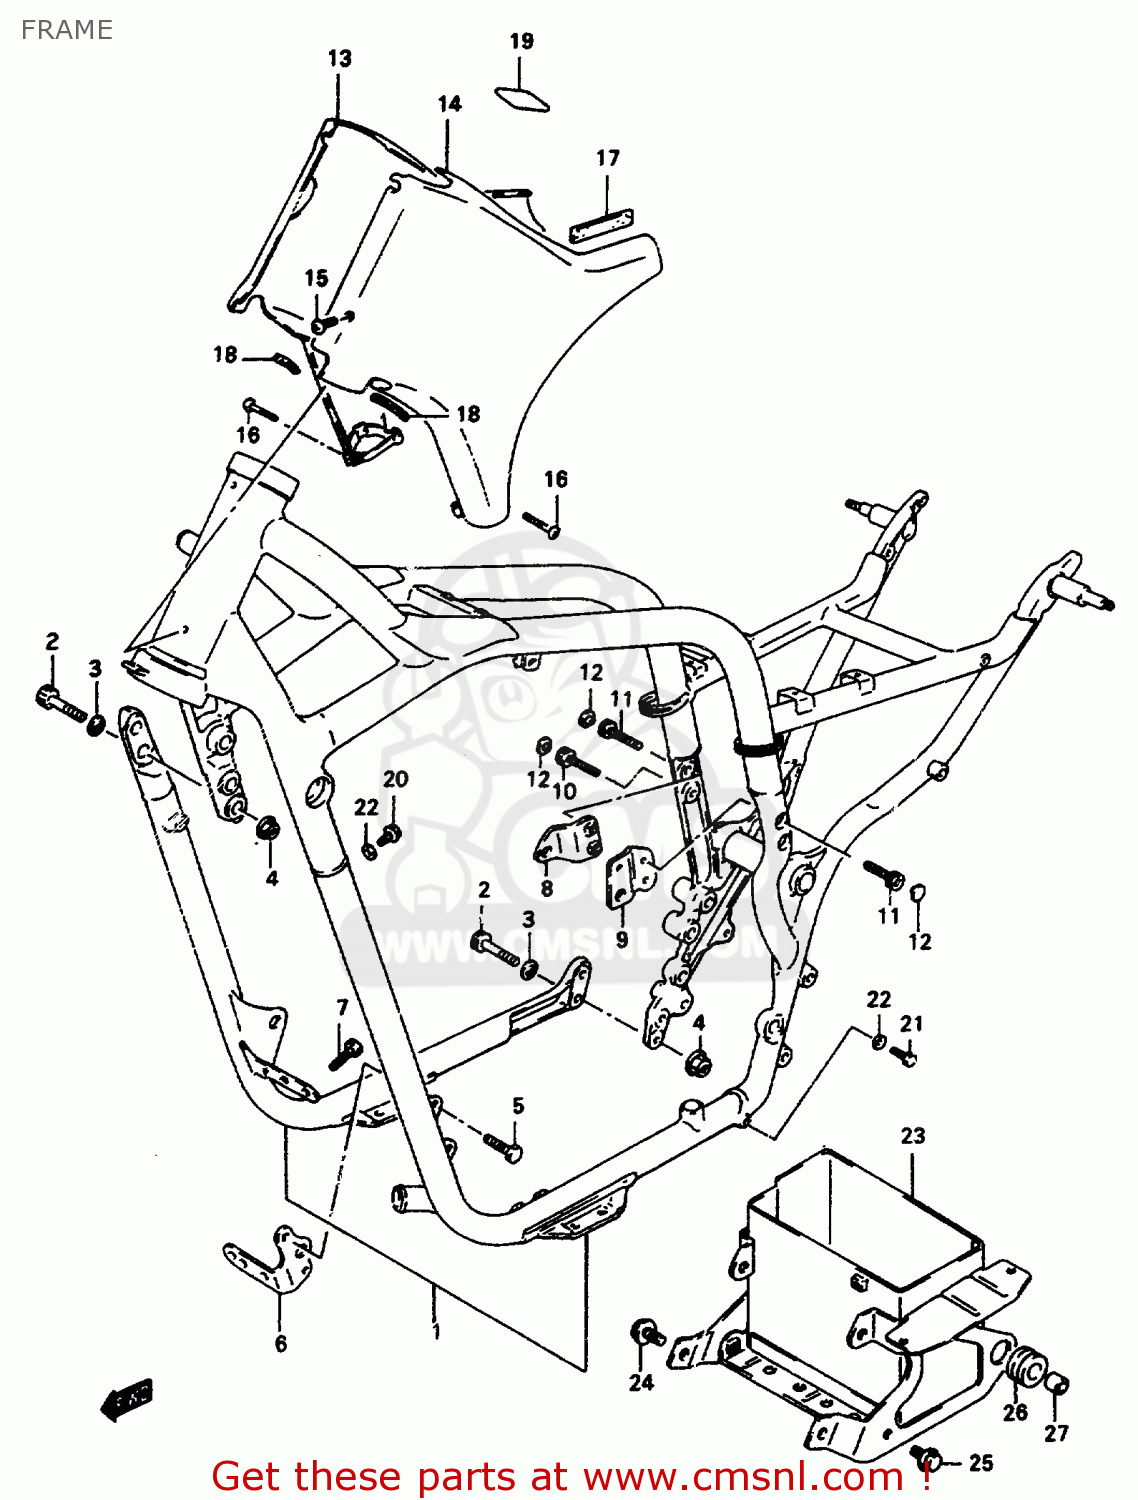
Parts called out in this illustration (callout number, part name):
1	FRAME SET
2	BOLT(10X33)
3	WASHER
4	NUT 10MM
5	BOLT
6	PLATE,ENGINE MOUNT NO.1,L
7	BOLT, UPPER
8	PLATE,ENGINE MOUNT NO.3,R
9	PLATE,ENGINE MOUNT NO.3,L
10	BOLT
11	BOLT(8X30)
12	CAP(OD:14.5)
13	COVER,FRM HD.,
14	COVER,FRAME HEAD,LEFT
15	SCREW 6X10
16	SCREW
17	PROTECTOR(80X80X2)
18	MOLDING
19	TAPE,FRAME HEAD COVER
20	UNION
21	BOLT
22	GASKET(6.2X11X1).2 (NAS)
23	HOLDER,BATTERY
24	BOLT
25	BOLT
26	CUSHION
27	BUSH
